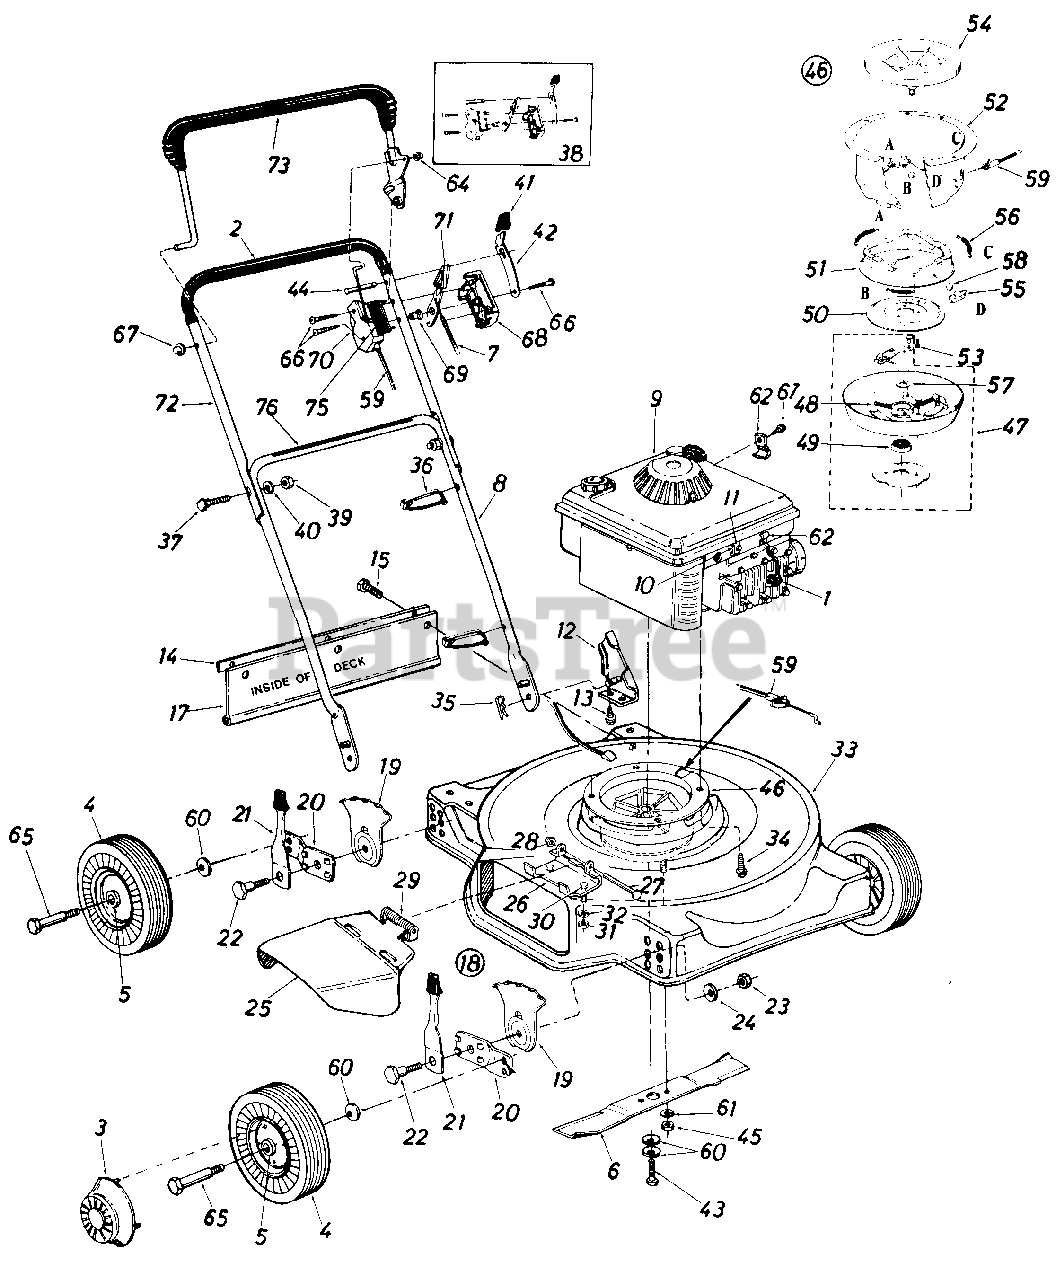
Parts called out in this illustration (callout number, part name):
1	Spark Plug Boot
3	Hub Cap
4	Wheel Ass'y. Comp.
5	Bearing
6	20" Blade
7	Throttle Control Wire-53"
8	Lower Handle
9	Engine
10	Casing Clamp
11	Hex B-Tap Scr. #10 x .62"
12	Handle Mount Brkt. Ass'y.-L.H.
13	Hex Wash. Hd. B-Tap Scr. 5/16-18 x .50" Lg.
14	Retaining Strip
15	Hex Wash. Hd. AB-Tap Scr. 1/4" x.62" Lg.
17	Rear Flap Ass'y.
18	Height Adj. Ass'y.-R.H.
19	Height Adj. Plate
20	Pivot Bar
21	Spring Lever w/Knob
22	Shld. Bolt .500" Dia. x .375
23	Hex Nut 3/8-16 Thd.
24	Bell-Wash. .39" I.D. x 1.4" O.D.
25	Chute Deflector Ass'y. Comp.
26	Deflector Hinge Plate
27	Pivot Pin
28	Cap Speed Nut 1/4" Rod
29	Torsion Spring
30	Hex Bolt 1/4-20 x .50" Lg.
31	Hex Nut 1/4-20 Thd.
32	L-Wash. 1/4" I.D.
33	20" Deck Ass'y.
34	Hex Wash. Hd. TT-Tap Scr. 3/8-16 x 1.00" Lg.
35	Intern. Cot. Pin 5/16" Dia.
36	Cable Tie
37	Curved Carriage Bolt 5/16-18 x 1.38" Lg.
38	Kit-Control Housing Comp.
39	Hex Nut 5/16-18 Thd.
40	L-Wash. 5/16" I.D.
41	Spring Lever Knob
42	Lock Out Spring
43	Hex Cent. L- Bolt 3/8-24 x 2.00" Lg.
44	Lock Pin .75" Dia. x 1.80
45	Special Hex Nut 5/16-24 Thd.
46	Blade Brake Clutch Ass'y. Comp.
47	Clutch Blade Housing Ass'y.
48	Comp. Spring .35" O.D. x 2.00" Lg.
49	Ball Brg. .669" I.D. x 1.574" O.D.
50	Clutching Cone
51	Brake Cup Cone
52	Clutch Housing
53	Hex Wash. TT-Tap Cl.-Scr. 1/4-20 x .75" Lg.
54	Fan Adapter
55	Ball Block
56	Extension Spring .35" O.D. x 1.75" Lg.
57	Fl-Wash. .690" I.D. x 1.060"
58	Steel Ball .500" Dia.
59	Clutch Cable-43"
60	Bell-Wash. .400" I.D. x .88"
61	L-Wash. 3/8" I.D.
62	Casing Clamp
64	Push Cap
65	Axle Bolt
66	Truss Mach. Hi-B Tap Scr. #12 x 1.50" Lg.
67	Cap Speed Nut 5/16" Rod
68	Control Panel Half
69	Control Disc Pin
70	Clutch Panel Half
71	Throttle Control Lever
72	Upper Handle
73	Control Handle Ass'y.
75	Control Label-Throttle
76	Instruction Label-Handle
